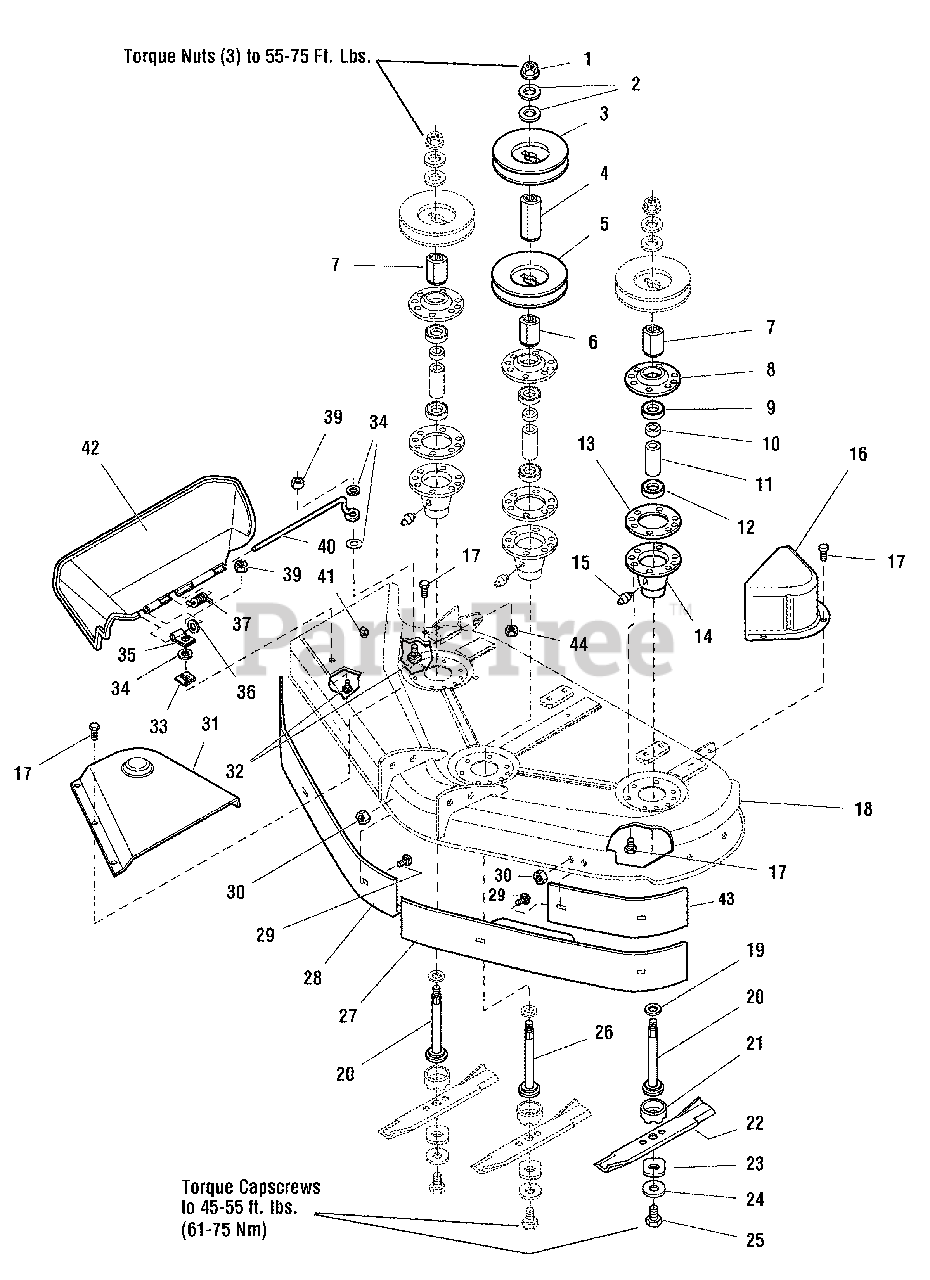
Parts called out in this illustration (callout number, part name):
1	NUT, Hex Flange, 9/16-18
2	WASHER, Bellville
8	COVER, Arbor Housing
13	GASKET, Foam
14	HOUSING ASSEMBLY, Arbor Bottom, w/Lube Fitting
15	FITTING, Lube
16	COVER, Arbor
17	CAPSCREW, Hex Washer Head, Taptite, 5/16-18 x 3/4, Black
18	HOUSING ASSEMBLY, 44" Front Cut
19	WASHER, Cup
21	SHIELD, Grass
22	BLADE, Mower, 16-1/8
23	WASHER, Hex, Special
24	WASHER, Black
25	CAPSCREW, Hex Head, 7/16-14 x 1-1/4, Black
26	SHAFT, Arbor
27	BAFFLE, Anti-Blowout, LH
28	BAFFLE, Anti-Blowout, RH
29	CARRIAGE BOLT, 5/16-18 x 3/4, Black
30	NUT, Hex Flange Whiz Lock, 5/16-18, Black
31	COVER, Arbor
32	CARRIAGE BOLT, 1/4-20 x 7/8, Black
33	NUT, Push, 1/4, Black
34	WASHER, 1/4, Black
36	WASHER, 5/16, Black
37	SPRING, Torsion
39	NUT, Hex, 1/4-20, Black, ESNA
40	ROD, Deflector, Front
42	DEFLECTOR, Plastic
43	BAFFLE, Anti Blowout, LH
44	NUT, Hex Whiz Lock, 5/16-18
